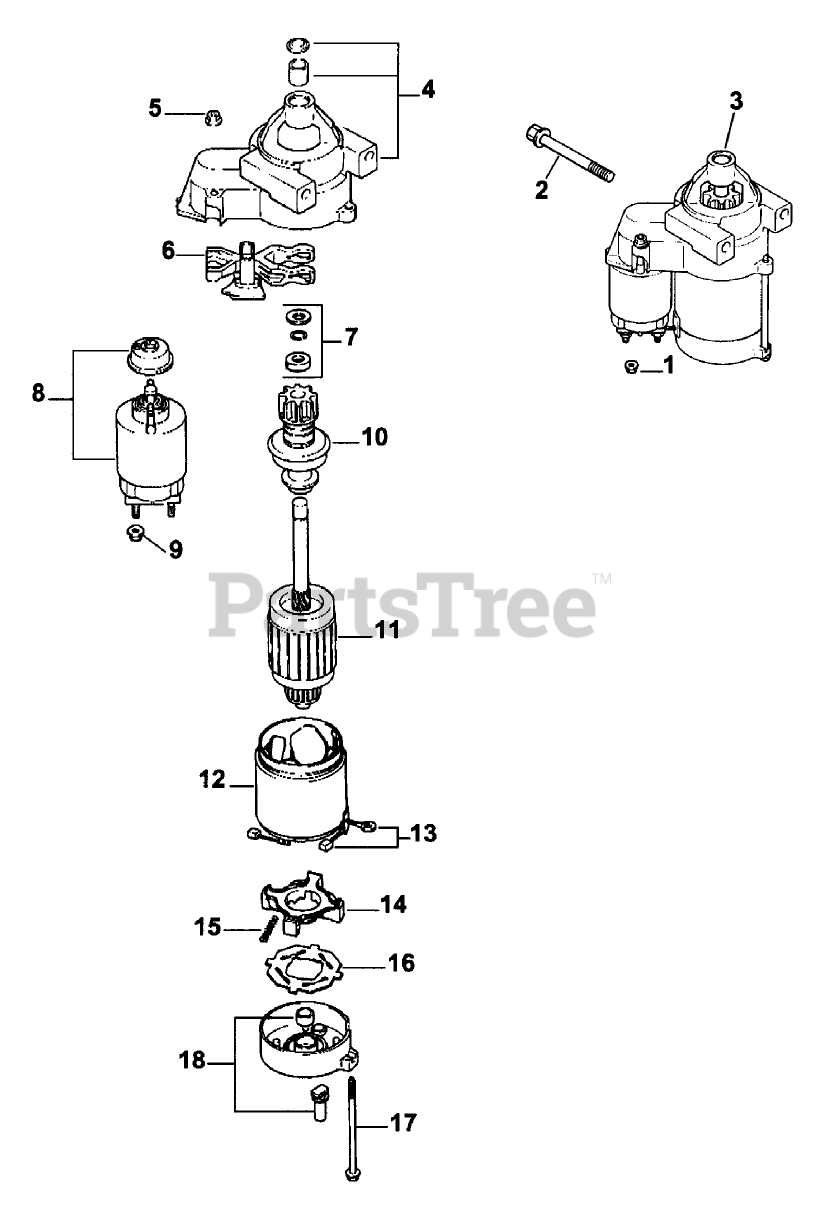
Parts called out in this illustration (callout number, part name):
1	Nut
2	Scew
3	Starter, solenoid shift (Includes 4-18)
4	Cap Drive End
5	Nut
6	Lever Starter Drive
7	Washer
8	Solenoid
9	Nut
10	Drive Pinion
11	Armature
12	Frame
13	Kit, brush (Includes 15)
14	Holder-Brush
15	Spring Brush
16	Insulator
17	Bolt
18	Cap-Commutator End
